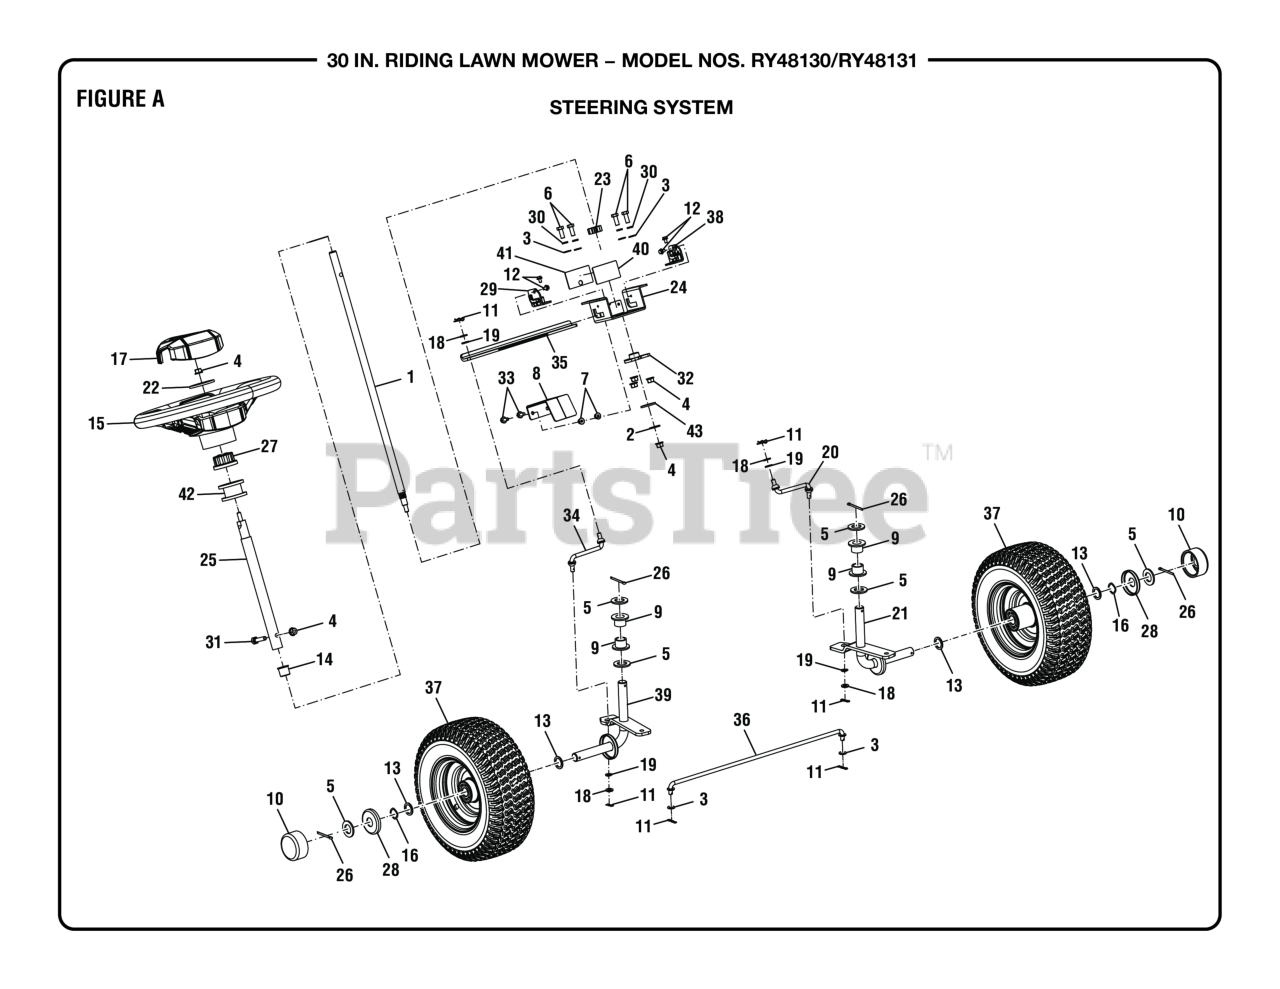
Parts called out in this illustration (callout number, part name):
1	Lower Steering Shaft
2	Washer (OD 24 x ID8.4 x 2t)
3	Washer (OD16 x ID8.4 x 1.6t)
4	Flange Nut (M8) (For Drive Motor Controller V)
5	Washer (OD37 x ID21 x 0.3t)
6	Hexagon Bolt (M8 x 20 mm)
7	Flange Nut (M6)
8	Rack Limiter
9	Steering Knuckle Bushing
10	Dust Cover, Front Wheel
11	Cotter Pin (8 mm)
12	Bolt (M5 x 8 mm, Hex Flange Hd.)
13	Washer (OD28 x ID20.5 x 2t)
14	Steering Shaft Bushing
15	Steering Wheel
16	Wavy Washer
17	Steering Wheel Cap
18	Tie Rod Washer (M8)
19	Wave Washer
20	Tie Rod (Left)
21	Steering Knuckle (Left)
22	Washer Plate
23	Steering Pinion Gear
24	Steering Rack Seat Bracket
25	Upper Steering Shaft
26	Cotter Pin (4 x 40 mm)
27	Spline Collar
28	Front Wheel Bearing Cover
29	Rack Bushing (Right)
30	Lock Washer (OD9.8 x ID8.5 x 5t)
31	Shoulder Bolt (M8 x 38 mm)
32	Steering Shaft Seat
33	Flange Bolt (M6 x 14 mm, Hex Hd.)
34	Tie Rod (Right)
35	Steering Rack
37	Front Wheel Assembly
38	Rack Bushing (Left)
39	Steering Knuckle (Right)
40	Rack Washer
41	Steel Pad
42	Column Spacer
